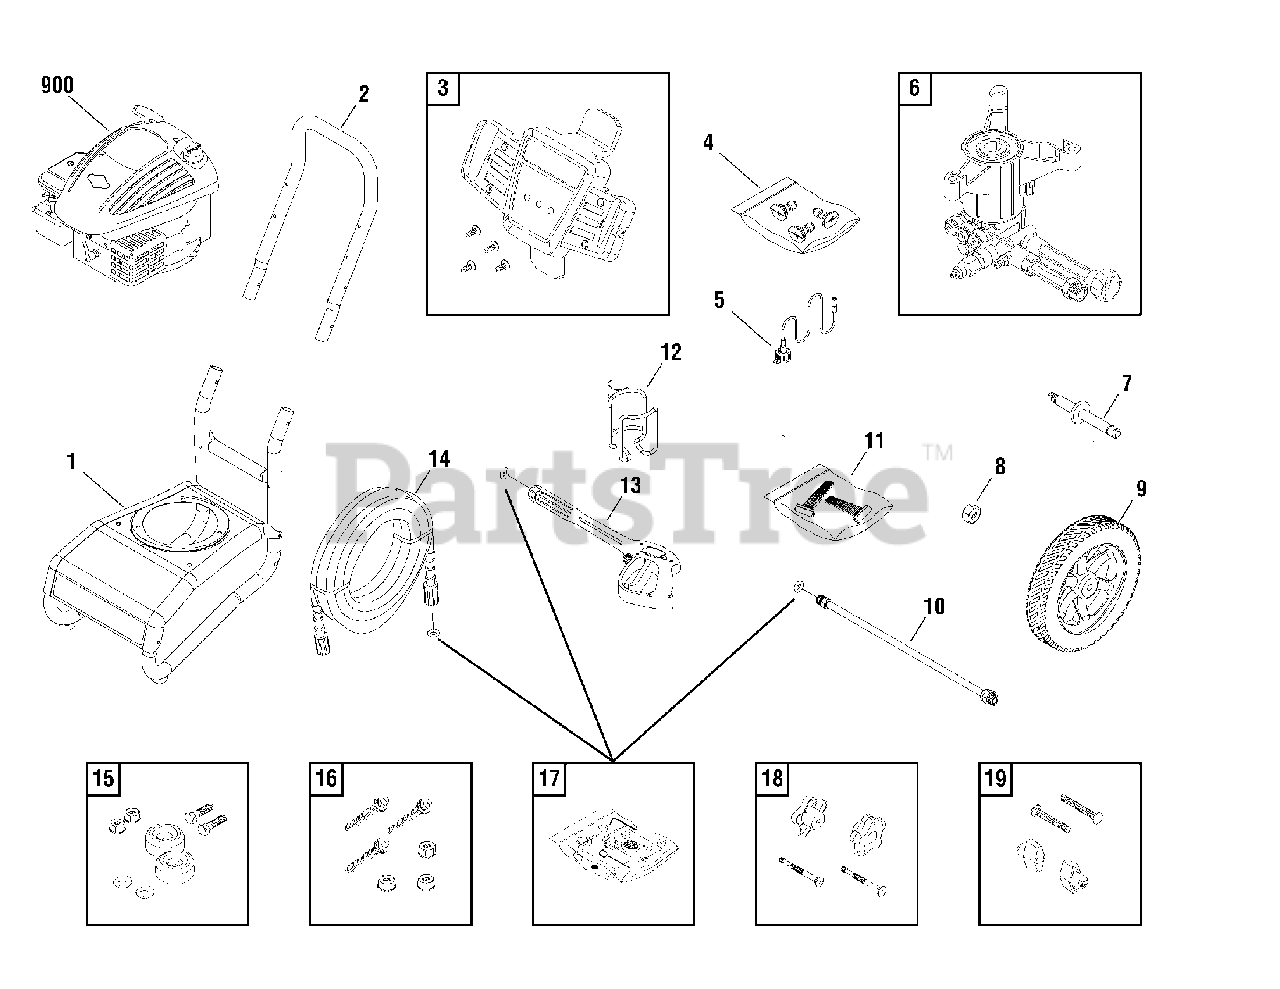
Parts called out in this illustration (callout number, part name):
1	BASE
6	PUMP
8	NUT
10	EXTENSION, QC
13	GUN
14	HOSE
15	MOUNT, Vibration
16	KIT, Hardware, Pump Mounting
17	KIT, O-Ring
900	* ENGINE, Briggs & Stratton
